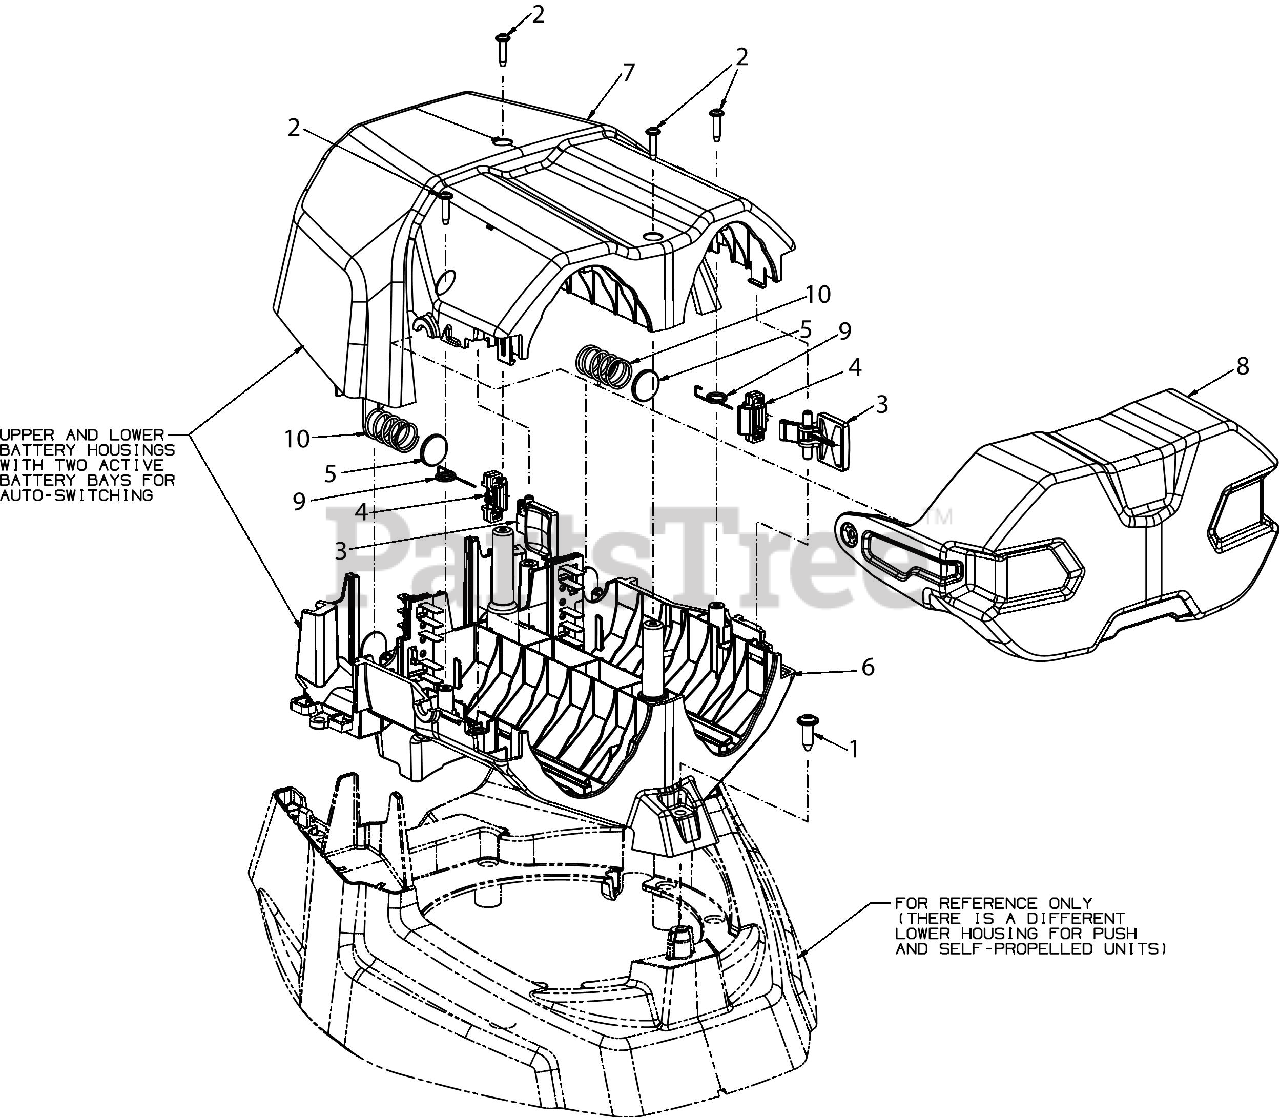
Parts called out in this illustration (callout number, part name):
1	SCREW - 1/4-10:.750
2	SCREW - #8-15:.710
3	BATTERY RELEASE BUTTON
4	BATTERY RELEASE LATCH
5	BATTERY RELEASE SPRING CAP
6	MIDDLE BATTERY HOUSING
7	DUAL BATTERY UPPER HOUSING
8	BATTERY HOUSING LID
9	TRIGGER SPRING
10	BATTERY RELEASE SPRING
